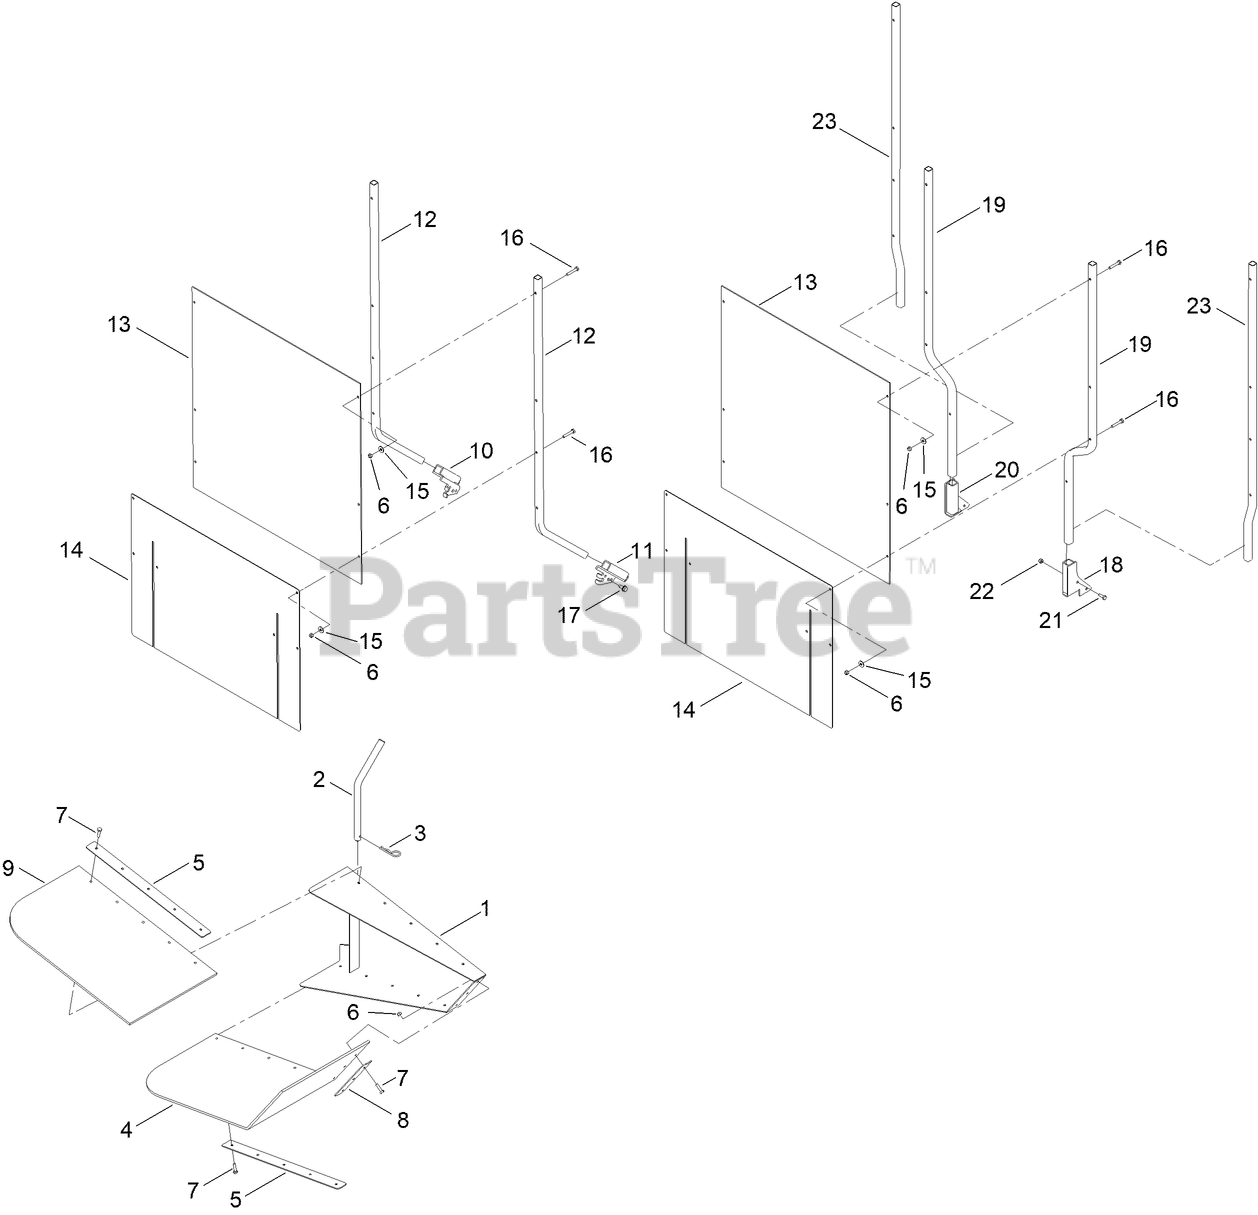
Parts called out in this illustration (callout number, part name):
1	CHIPPER GUARD ASM
2	PIN-HINGE
3	PIN-HAIR
4	GUARD-SKIRT, REAR
5	CLAMP-SKIRT
6	NUT-HEX
7	SCREW-HH
8	CLAMP-SKIRT
9	GUARD-SKIRT, FRONT
10	BRACKET-SUPPORT, RH
11	BRACKET-SUPPORT, LH
12	SUPPORT-SHIELD
13	SHIELD-LEXAN
14	SKIRT-PROTECTOR
15	WASHER-FLAT
16	SCREW-HH
17	SCREW-HWHTF
18	BRACKET-SUPPORT, LH
19	SUPPORT-TUBE, SHIELD
20	BRACKET-SUPPORT, RH
21	SCREW-HH
22	NUT-LOCK, NI
23	TUBE-SUPPORT, SHIELD
